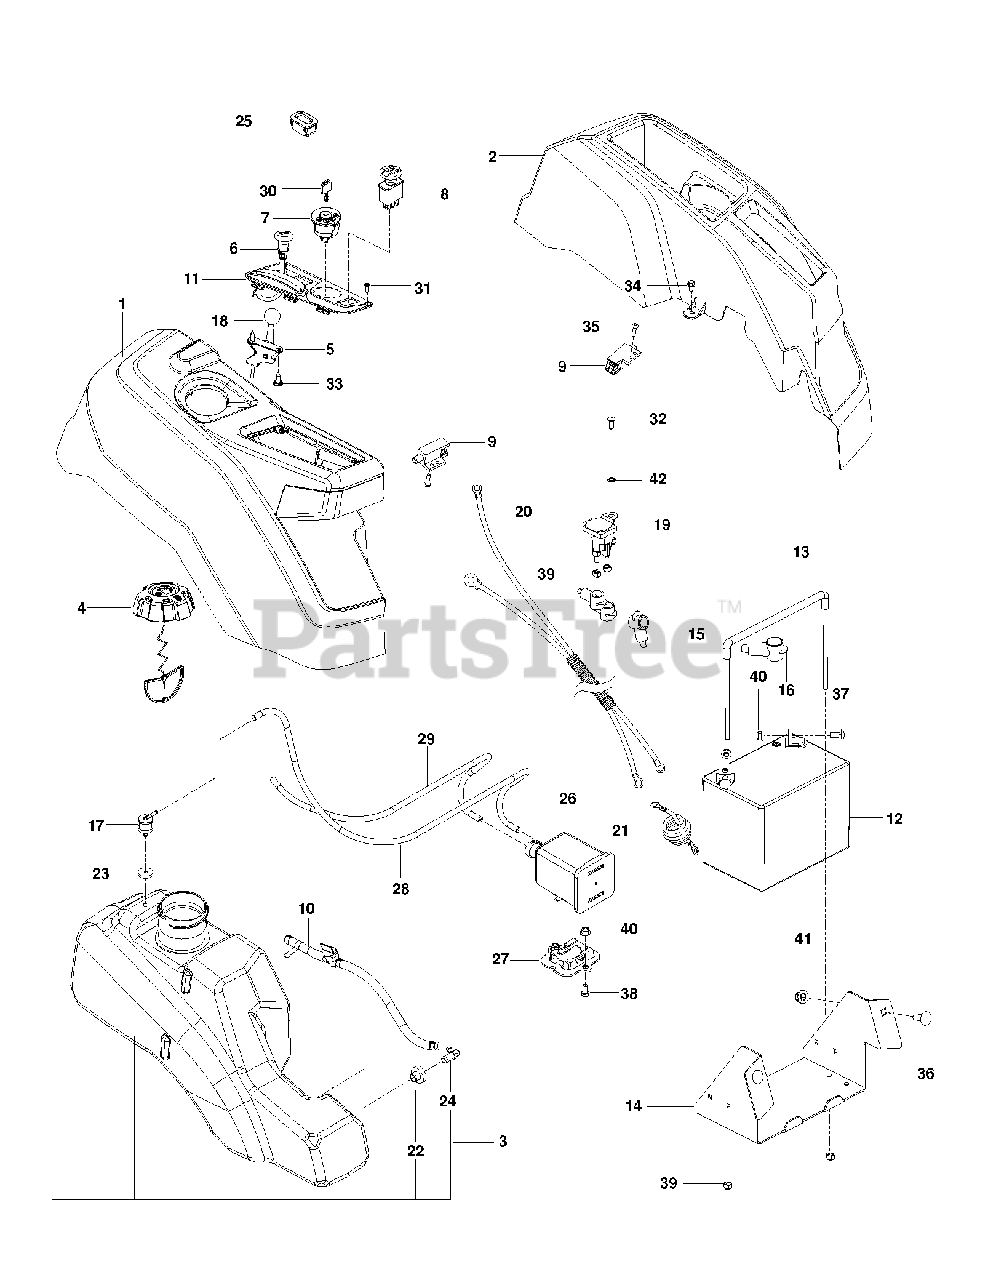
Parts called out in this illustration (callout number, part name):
1	CONSOLE.ASSY.RZ.REFRESH.RH
2	CONSOLE.LH.ASM
3	ASM.FUEL.TANK.LG.3".W/O SHIELD
4	CAP ASSY FUEL 3" GRAY
5	THROTTLE CABLE
6	CHOKE.PUSH-IN.STYLE
7	RP IGNITION SWITCH
8	RP SWITCH.PTO.8.TERMINAL.RED
9	SWITCH.INTLK.RZ.RFRSH.BUTTON
10	FUEL.HOSE.SHUT.OFF.ASM.10".3"
11	CONTROL.PANEL.RZ.REFRESH.RH
12	BATTERY, 12 V 330 AMP
13	BATTERY TIE DOWN ASSEMBLY
14	BOX BATTERY RZ BLACK
15	TERMINAL COVER
17	VALVE.FUEL.CHECK
18	KNOB.ROUND.BALL.BLACK
19	SOLENOID.W/BRASS.PLUNGER
20	HARNESS.BTTRY.CABLE.RZ.REFRESH
21	CABLE POSITIVE, LONG
22	BUSHING OUTLET T
23	GROMMET.ROV.SENTEC
24	STEM FUEL TANK
25	GUAGE.SRVCMNDR.HRMTR.
26	CANNISTER, CARBON
27	BRACKET, CANISTER
28	HOSE.3/16".VAPOR.LINE.23"LGTH
29	HOSE.3/16".VAPOR.LINE.36"LGTH
30	KEY MLD GEN DELTA
31	SCREW 6-19X.437
32	SCR 1/4-20 X 5/8 BTN SKT HD ZD
33	SCREW.PAN.HEAD.#10
34	SCREW
35	SCR #10-24 X .75 SKT HD BLK
36	RHSNB 3/8C X 1
37	BOLT 5/16-18 X3/4 ZN/YEL GR 5
38	HCS 5/16-18 X 5/8 GR 5 ZD
39	LOCKNUT.NYLOC.1/4-20
40	5/16-18 NYLOC FLANGE NUT
41	NUT 3/8-16 HEX FLG NYLOC ZD
42	WASHER 1/4 INT TOOTH
